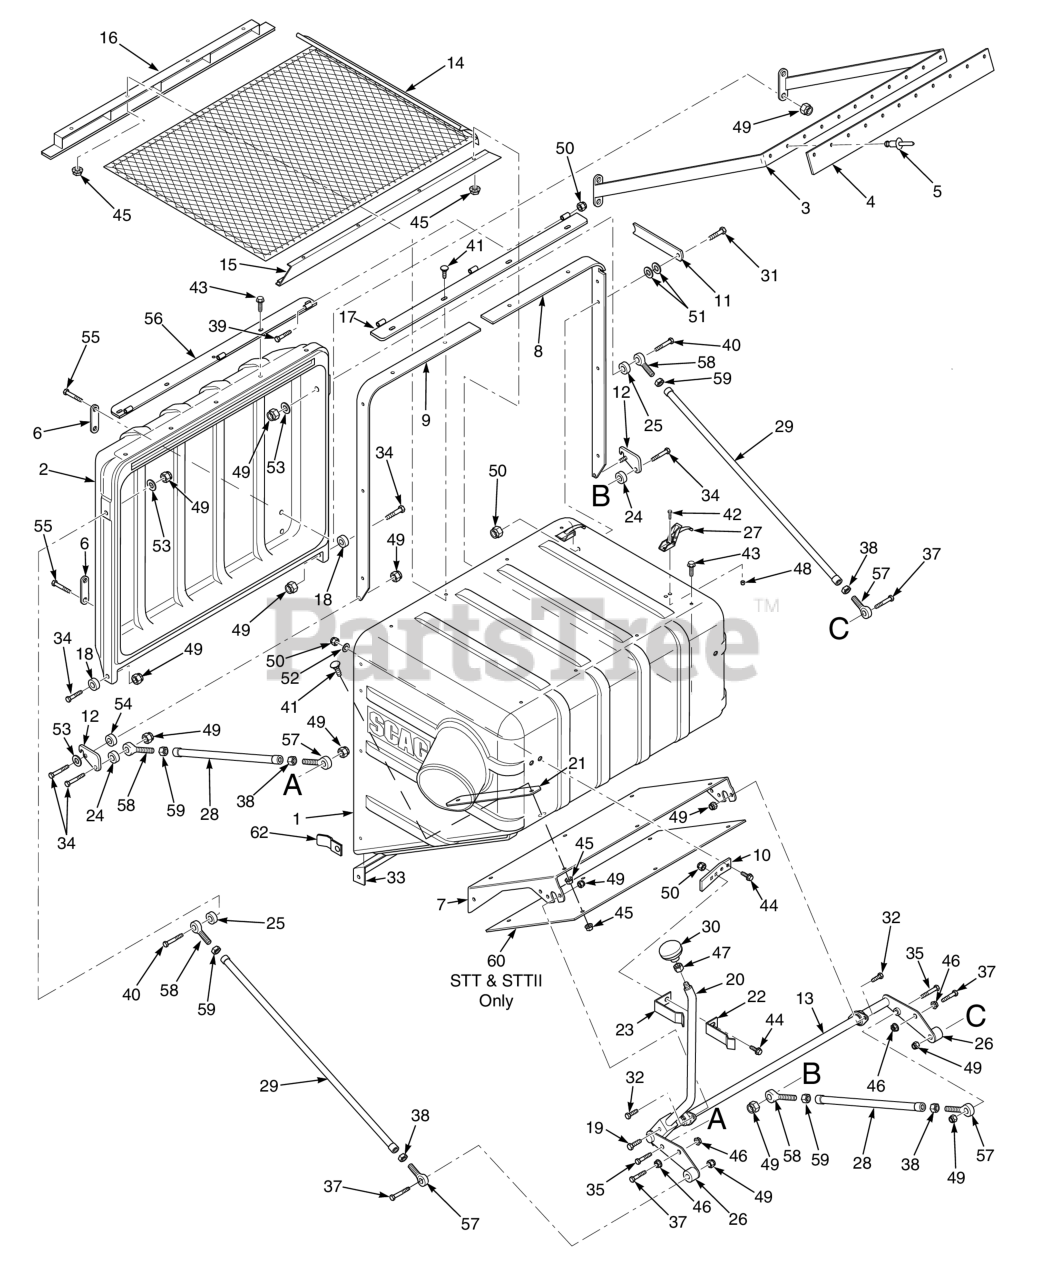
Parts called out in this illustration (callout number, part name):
1	Hopper, GC-STT-CS
2	Door, GC-CS
3	Sweeper Weldment, GC-CS
4	Pad, Rubber
5	Pop Rivet, 3/16 x .652"
6	Plate, Stiffener
7	Support Frame, Hopper
8	Hinge Bracket, L.H.
9	Hinge Bracket, R.H.
10	Mounting Bracket, Dump Handle Latch
11	Latch, Door Prop
12	Plate, Latch
13	Bellcrank Weldment, Upper
14	Debris Screen Weldment
15	Screen Support Weldment, Rear
16	Screen Support Weldment, Front
17	Hinge Weldment, Hopper
18	Spacer, Idler Bearing
19	Bolt, Hex Head 5/16-18 x 1-1/2" - Front
20	Rod, Dump Lever GC-SCZ-CS
21	Retainer Strip, Hopper
22	Latch, Dump Rod Inner
23	Latch, Dump Rod Outer
24	SPACER, IDLER
25	SPACER, J PULL ROD
26	SPACER, J-PULL ROD
27	LATCH, HOOD
28	Linkage Assembly, Lower
29	Linkage Assembly, Upper
30	Knob, Cutter Deck Release
31	Bolt, 5/16 - 18 x 1 - 1/4" Hex Head
32	Bolt, Hex Head, 3/8-16 x 3/4"
33	Bracket, Lower Stiffener
34	Bolt, Hex Head 3/8-16 x 1-1/2" B&S 32BV
35	Bolt, Hex Head 3/8-16 x 1-3/4" (Kohler EFI)
36	Alignment Bracket, GC-CS
37	Capscrew, Hex Head 3/8-16 x 2.0"
38	Nut, 3/8-24 UNF R.H. Thread
39	Bolt, Hex Head 5/16-18 x 3-1/2"
40	Bolt, Hex Head, 3/8-16 x 3-1/2"
41	Bolt, Carriage 5/16-18x1" (large frame units only)
42	SCREW, PHILLIPS WASHER HEAD #10-32 X 1/2"
43	Capscrew, 5/16-18 x .75 Serrated Flange Hex Head
44	Cpscrw, 5/16-18 x 1"Serrated Flange Hex Head
45	Nut, Serrated Flange 5/16-18 (Right Front Engine Mounting, Briggs and Kohler Only)
46	NUT, 3/8-16 SERRATED FLANGE HEX HEAD
47	Nut, Jam 3/8-16
48	HEX NUT, ELASTIC STOP LOCK # 10-32
49	HEX NUT, ELASTIC STOP LOCK, 3/8-16
50	HEX NUT, ELASTIC STOP LOCK, 5/16-18
51	Socket Head Capscrew #8-32 x 1/2"
52	Flatwasher, 5/16-.375 x .875 x .083 (35BV & 37BV-EFI)
53	Flatwasher, 3/8" Special (.391 x .938 x .105)
54	Bushing, Hopper Latch GC-CS
55	Bolt, Hex Head 3/8-16 x 3" - 52"
56	Hinge Weldment, Door
57	Rod End Male, 3/8-24 R.H. Thread
58	Rod End Male, 3/8-24 L.H. Thread
59	Nut, 3/8-24 UNF-2B LH Thread
60	Heat Shield, GC-STT Only
